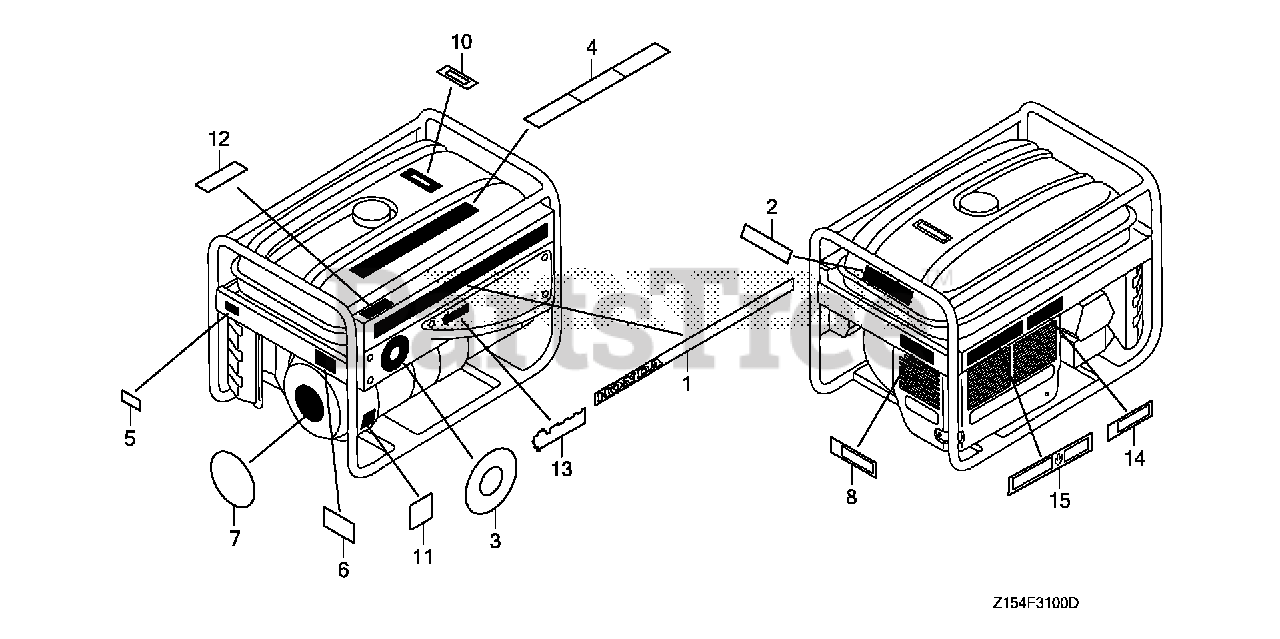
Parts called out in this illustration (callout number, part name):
1	MARK, EMBLEM (EP2500CX)
2	MARK, SPEC (CX-A)
3	MARK, ENGINE SWITCH
4	LABEL, OPERATOR WARNING
5	MARK, CHOKE
6	LABEL, OIL ALERT
7	MARK, HONDA
10	PLATE, FUEL INDICATION
11	MARK, OIL CHECK
14	MARK, EX. CAUTION
15	LABEL, EX. WARNING (E)
